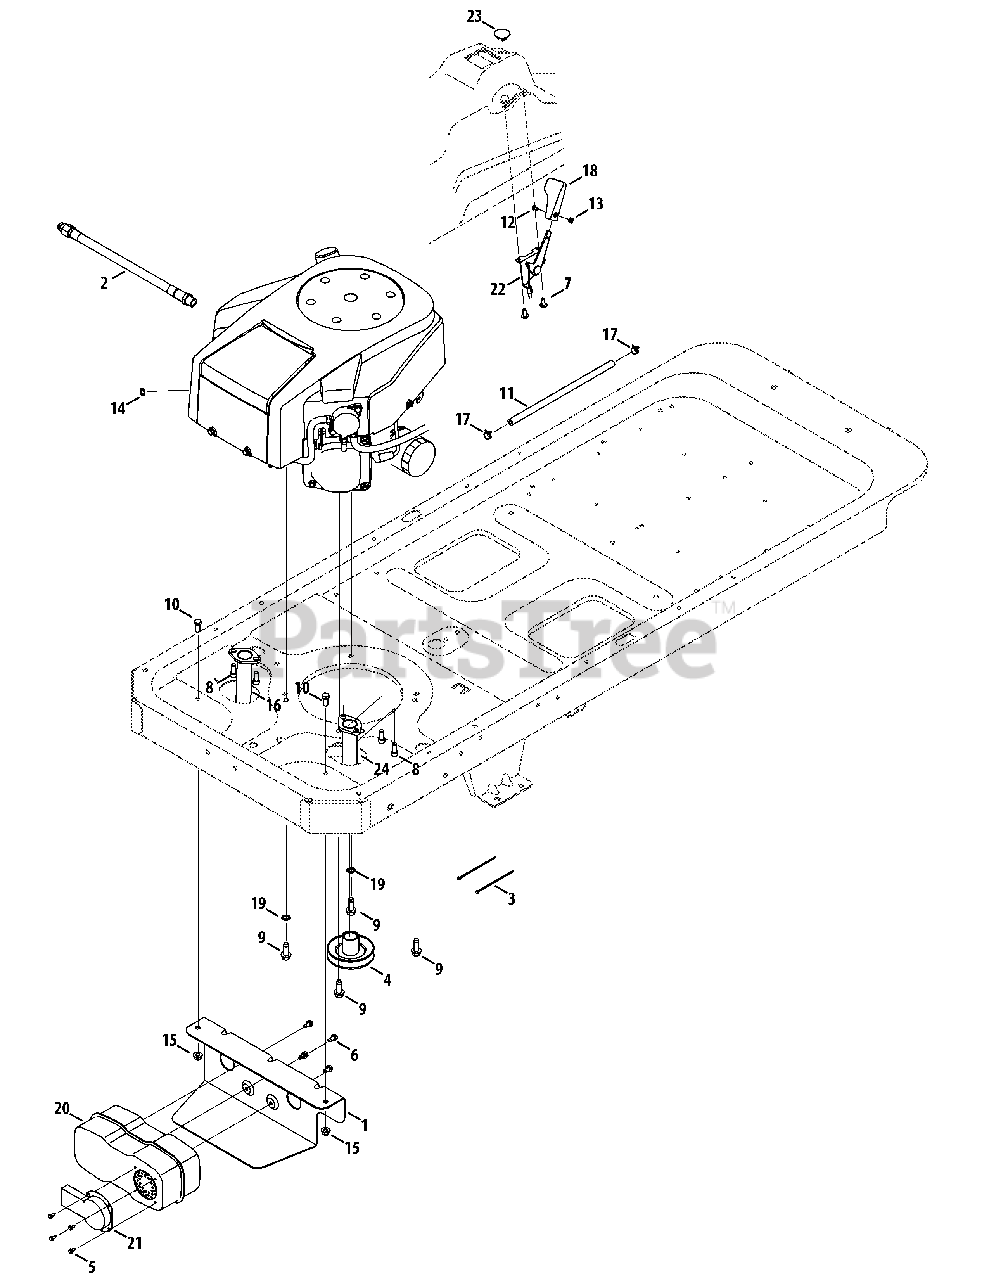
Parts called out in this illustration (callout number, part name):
1	Muffler Mount Bracket
2	Oil Drain Hose
3	Cable Tie
4	PTO Pulley
5	Hex Washer Screw, #8-18 x 0.500
6	Hex Washer Screw, 1/4-20 x 0.500
7	Screw, 1/4-14 x 0.625
8	Socket Screw, 5/16-18 x .750
9	Hex Washer Screw, 3/8-16 x 1.250
10	Hex Screw, 5/16-18 x .75
11	Low Permeation Fuel Hose
12	Machine Screw, #8-32 x 0.375
13	Hex Nut, #8-32
14	Sems Nut, 1/4-20
15	Flange Lock Nut, 5/16-18
16	Exhaust Pipe - LH
17	Hose Clamp, .490
18	Throttle Control Knob
19	External Tooth Lock Washer, 3/8
20	Dual Inlet Muffler
21	Muffler Deflector
22	Throttle/Choke Control Cable
23	Choke Plug
24	Exhaust Pipe - RH
